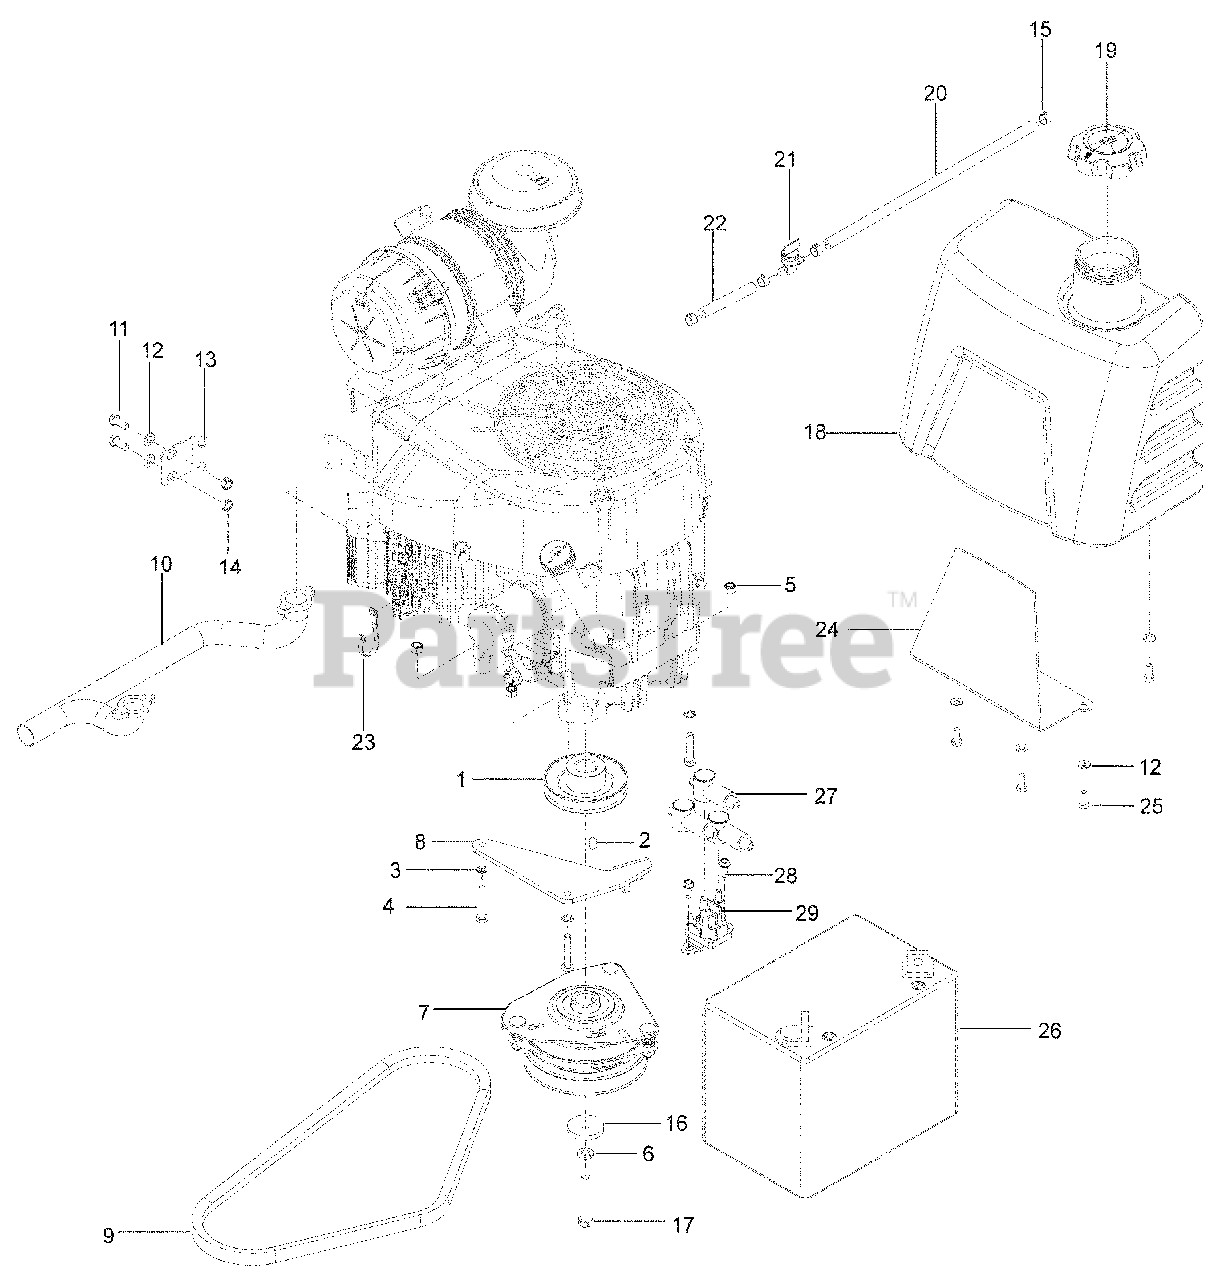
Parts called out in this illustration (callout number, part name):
2	KEY ¼ SQ x ½
3	LOCK WASHER 5/16 STAR
4	HCS 5/16-18 x 1¾
5	NUT 5/16-18 HEX NYLOC
6	WASHER 7/16 SLW
7	CLUTCH 90 FT/LB
8	CLUTCH STOP
10	MANIFOLD, EXHAUST
11	HCS 5/16-18 x ¾
12	WASHER 5/16 SAE FLAT
13	BRACKET, MUFFLER
14	NUT 5/16-18 HEX CNTRLK
16	WASHER, HEAVY
17	HCS 7/16-20 x 2½
18	TANK, FUEL
19	CAP, FUEL TANK
20	FUEL LINE, 12"
21	VALVE, FUEL
22	FUEL LINE, 3½"
25	HCS 5/16-18 x ¾
26	BATTERY, DRY
28	SCREW ¼-20 x 5/8 SLF TAP
